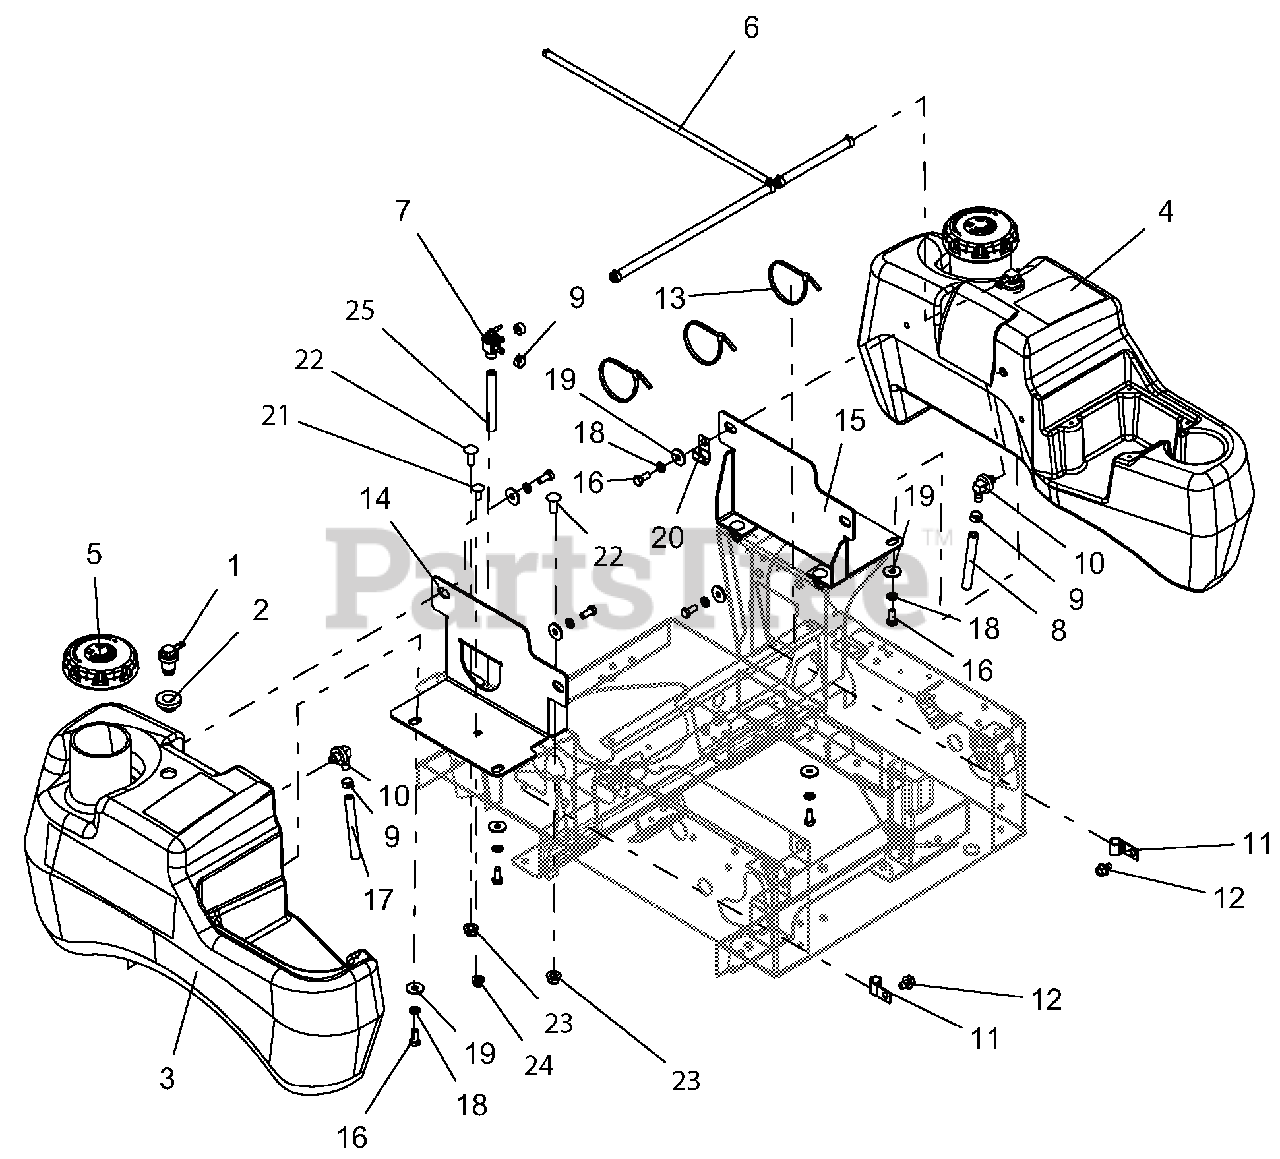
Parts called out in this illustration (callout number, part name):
1	VALVE, COMBINATION
2	GROMMET, REMOTE VENT NITRILE
3	TANK, GAS - RH MEDIUM GRAVELY
4	TANK, GAS - LH MEDIUM GRAVELY
5	CAP, FUEL VENT-IN AUTOLOCK
6	PT100, KOHLER FUEL LINE ASSY
7	VALVE, FUEL
8	.25 LOW-PERM GAS HOSE 40.00" LG - LH TANK TO VALVE
9	CLAMP, FUEL LINE
10	ASS'Y, SMALL/ MED TANK FUEL PICK-UP
12	SCR-TAP .38-16X.50 HWH TR YWZ
13	CABLE, TIE 5.50 LG
14	BRKT, RH MEDIUM FUEL TANK MTG (RED)
15	BRKT, RH MEDIUM FUEL TANK MTG (RED)
16	BLT-HEX .31-18X.75 GR5 YWZC
17	.25 LOW-PERM GAS HOSE 18.50" LG - RH TANK TO VALVE
18	WSHR-LK .31X.078 REG YWZC
19	WSHR-FL-STL .328X1.00X.094 YWZC
20	CLAMP, J
21	BLT-RDHDSQNK .31-18X.75 G5 YWZC
22	BLT-RDHDSHSQNK.38-16X1.0 G5YZ
23	NUT-LK-NYL-FLG .38-16 YWZC
24	NUT-LK-NYL-FLG .31-18 YWZC
25	.25 LOW-PERM GAS HOSE 7.50" VALVE TO ENGINE
